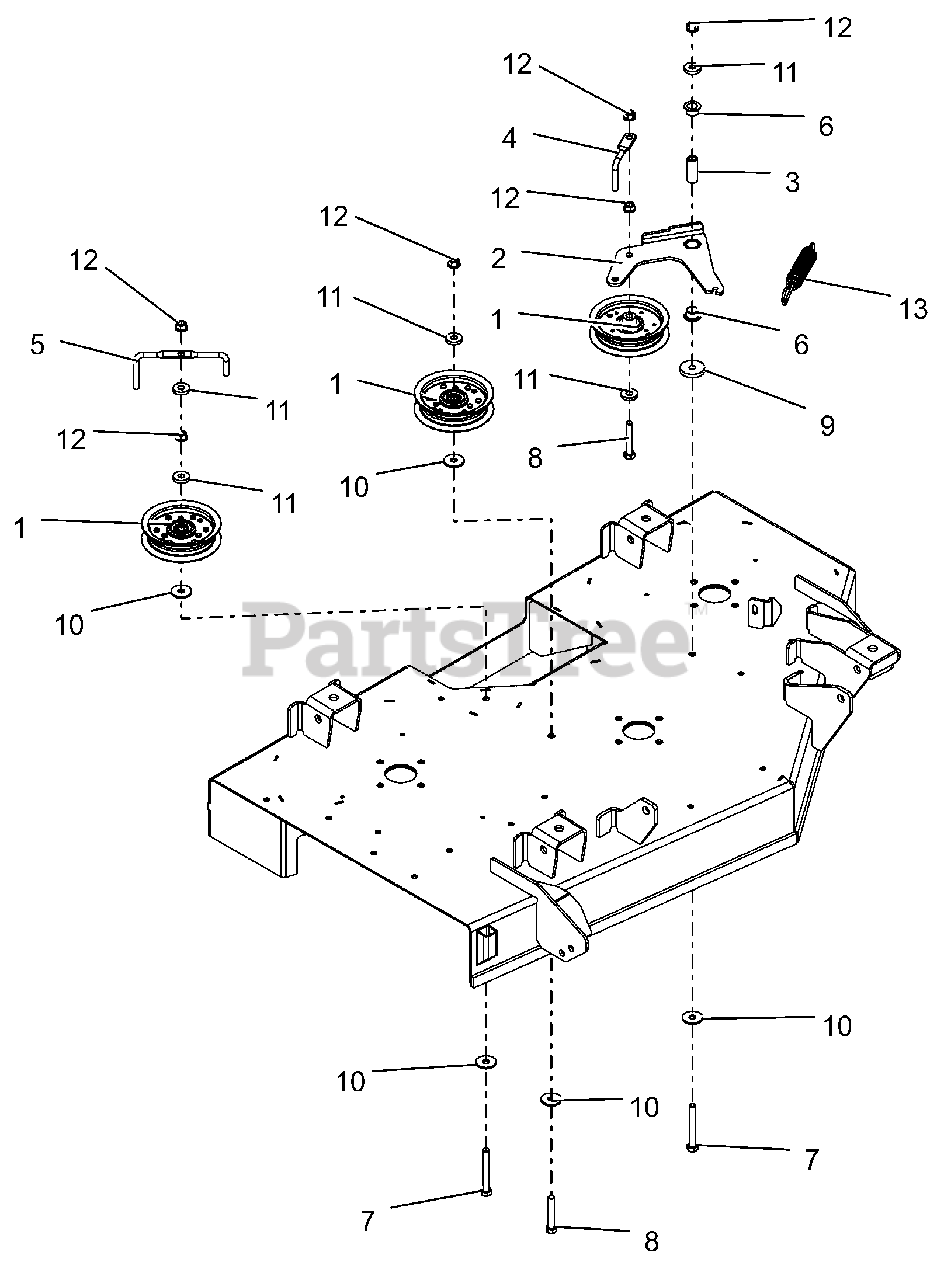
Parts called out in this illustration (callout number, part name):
1	ASM, IDLER 4"
2	WLDMT, IDLER ARM-42"
3	SPACER, .375IDX.625ODX1.66 PM
4	WIREFORM, BELT FINGER
5	WIREFORM, BELT FINGER
6	BSHG-FLG, .625X.750X.500X1.00
7	BLT, HEX .38-16X3.00F G5 ZCC
8	BLT,HEX .38-16X2.25 G5 ZCC
9	WSHR, FLT .406X1.50X.245 ZCC
10	WSHR FL STL .406X1.25X.10ZC120
11	WSHR, FLT .406X1.00X.188 ZCC
12	NUT-LK-CTR-FLG .375-16 GF ZCC
13	SG-TENS .135X.98X6.0 WLD 62
